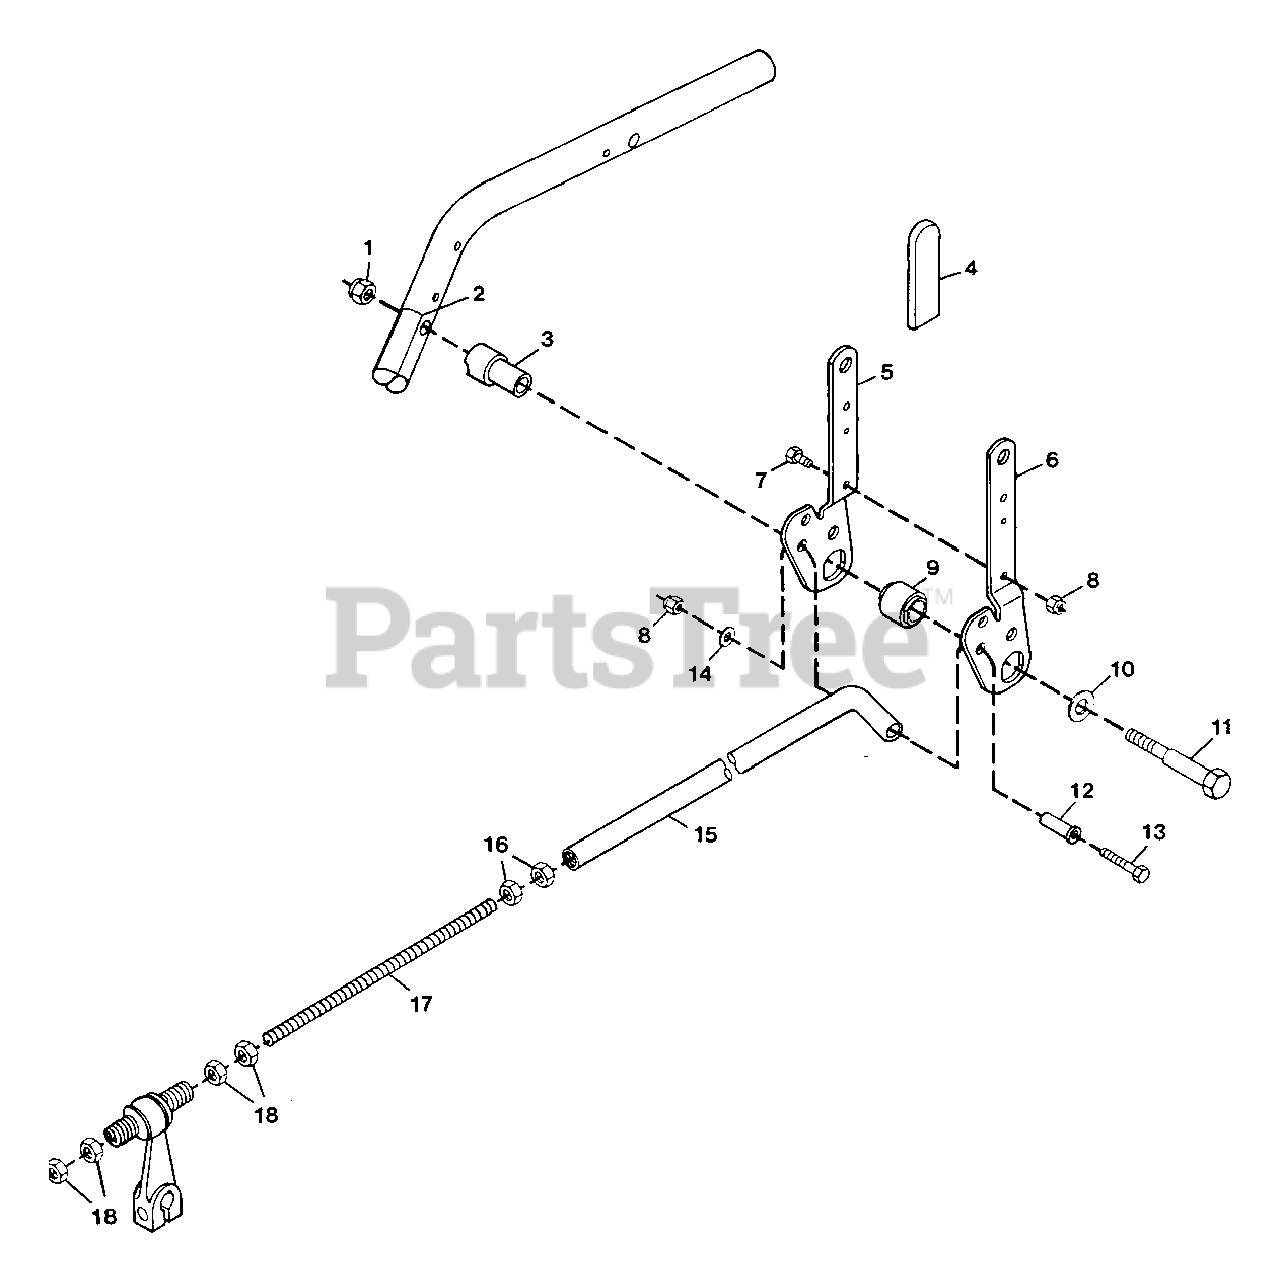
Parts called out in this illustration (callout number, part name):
1	Nut, Lock 3/8-16
2	Decal, Gear Shift
3	Pivot, Hand Lever L.H.
4	Grip, Handle
5	Handle, Control R.H.
6	Handle, Control L.H.
7	Bolt, Hex 1/4-20x.625
8	Nut, Lock 1/4-20
9	Bushing, Handle
10	Washer, Flat .531x1.062x.095
11	Bolt, Hex Step
12	Bushing, Oper. Presence Handle
13	Bolt, Hex 1/4-20x1.50
14	Washer, Flat .281x.625x.065
15	Rod, Control Hi-Lo
16	Nut, Hex 3/8-16
17	Rod, Control Extension
18	Nut, Jam 3/8-16 Hex
